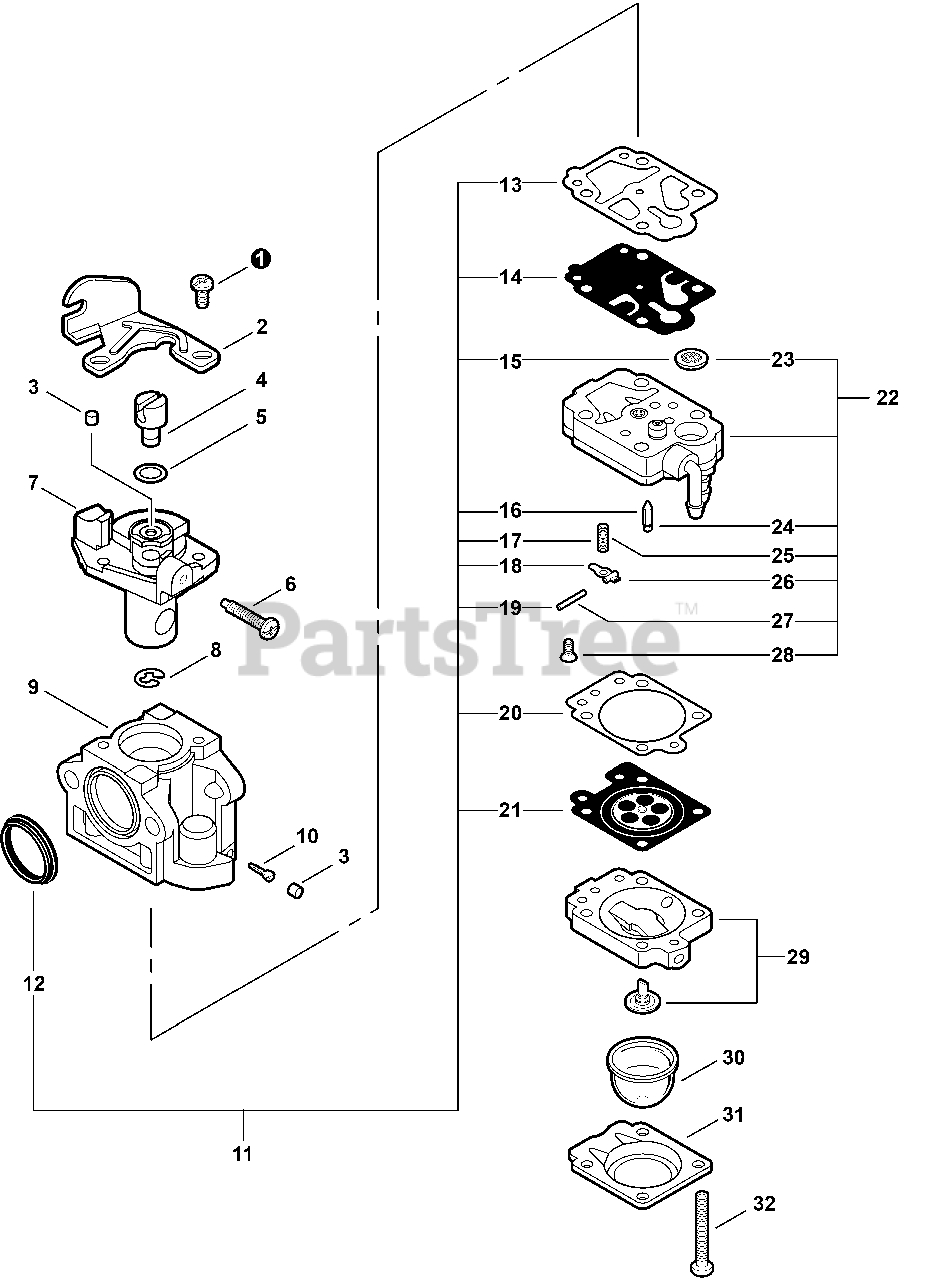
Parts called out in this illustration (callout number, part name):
2	BRACKET, THROTTLE CABLE
9	BODY, CARBURETOR
10	NEEDLE, HIGH SPEED
11	REPAIR KIT, CARBURETOR
12	RING, PACKING
13	GASKET, PUMP
14	DIAPHRAGM, PUMP
15	STRAINER
16	VALVE, INLET NEEDLE
17	SPRING, METERING LEVER
18	LEVER, METERING
19	PIN, METERING LEVER
20	GASKET, DIAPHRAGM
21	DIAPHRAGM, METERING
22	BODY ASSY, PUMP
23	STRAINER
24	VALVE, INLET NEEDLE
25	SPRING, METERING LEVER
26	LEVER, METERING
27	PIN, METERING LEVER
29	BODY ASSY, PURGE
30	BULB, PURGE
31	RETAINER, PURGE BULB
